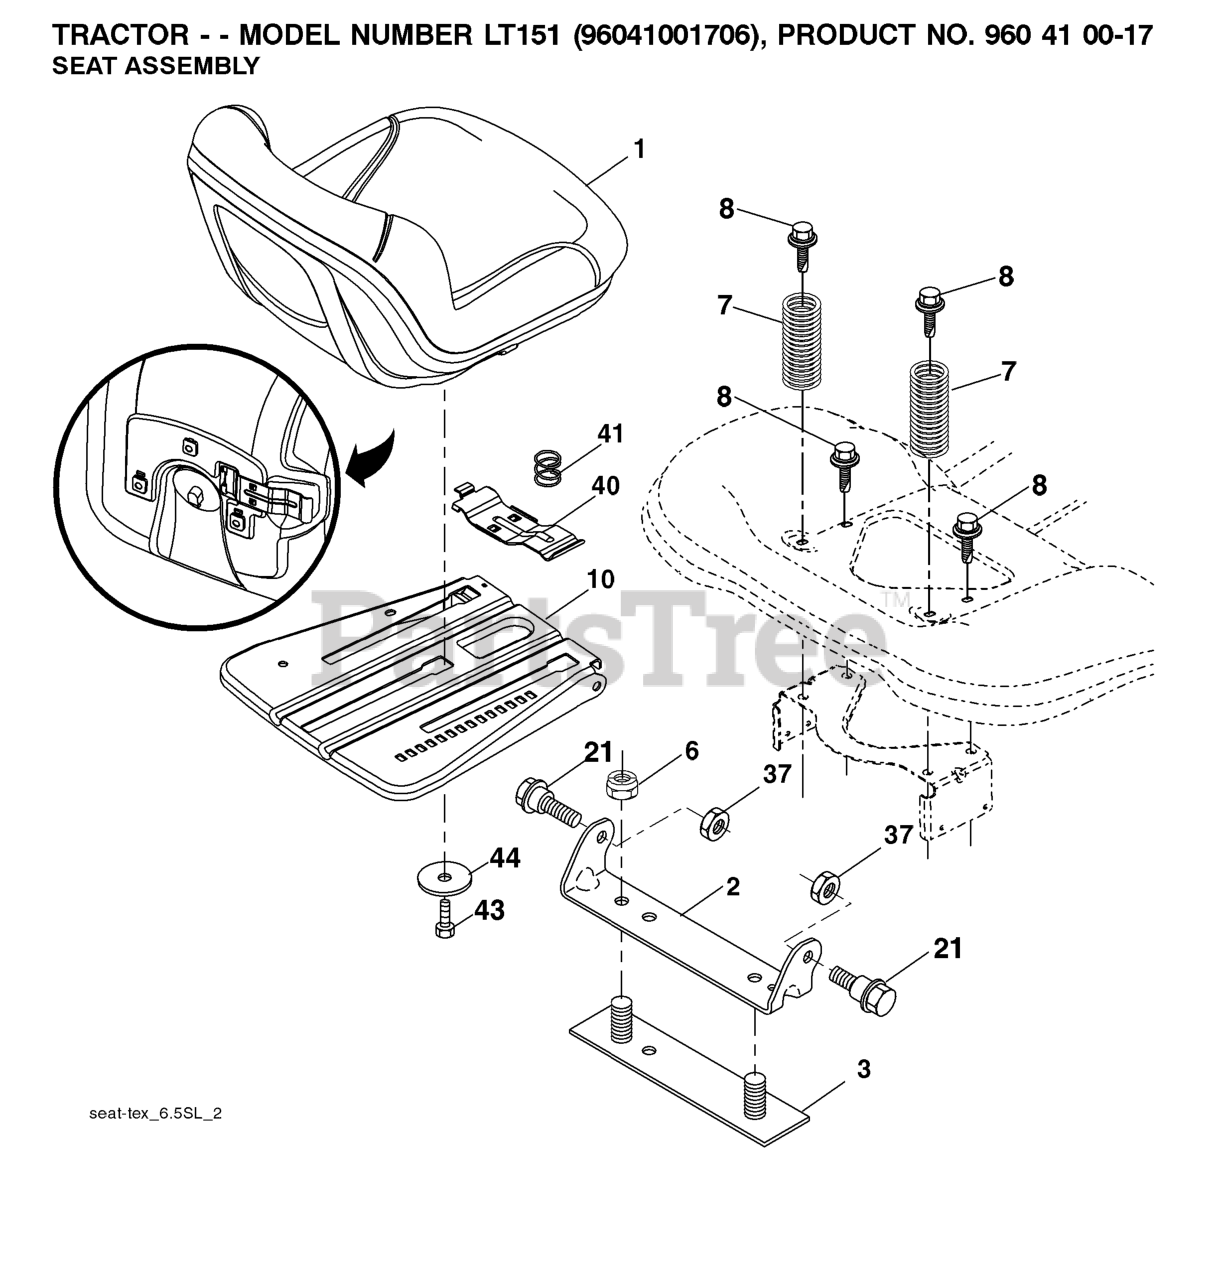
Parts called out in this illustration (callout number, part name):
1	SEAT.TH130.GRY.MILSCO.
2	BRKT.PIVOT.FENDER
3	STRAP
6	NUT
7	SPRING COMPRESSION
8	BOLT.5/16-18UNCX3/4 W/SEMS.BLK
10	PAN.ASM.SEAT.3PT
21	BOLT.SHOULDER.5/16-18
37	NUT.71038.31-18.HEX.NYLOCK
40	HANDLE.SLIDE.SEAT.TEX.BLACK
41	SPRING.LATCH.SEAT.TEX
44	WASHER 13/32 X 2-3/8 X 12GA
